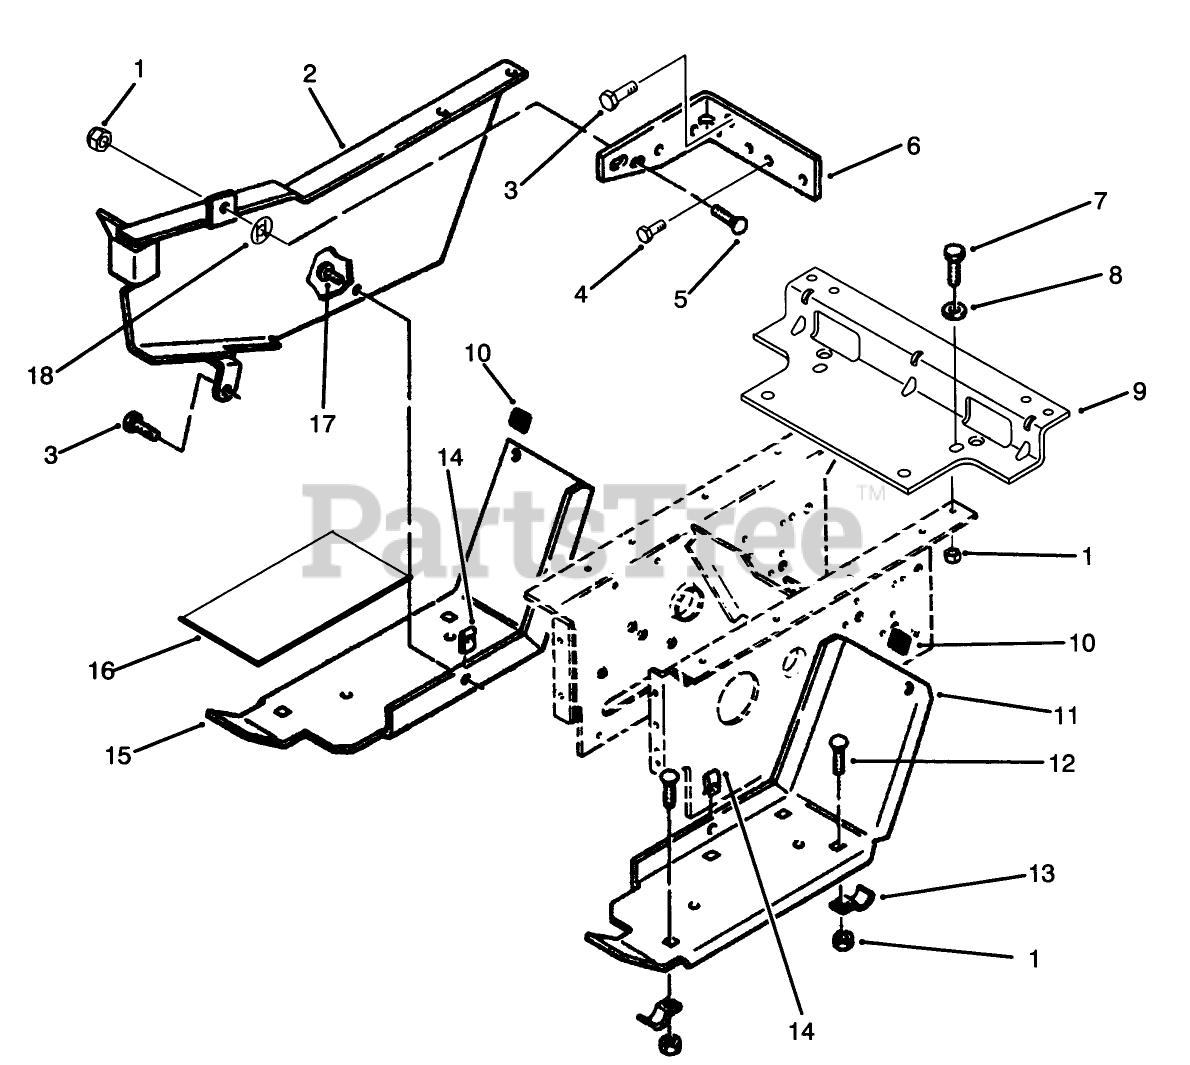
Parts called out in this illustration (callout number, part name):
1	NUT-LOCK, NI
2	GUARD - BELT WA *R
3	SCREW
4	Bolt
5	BOLT-CARR
6	BRACKET-BELT*B
7	SCREW-HH
8	WASHER-PLAIN
10	BUMPER
11	FOOTREST LH *R
12	BOLT-CARR
13	BRACKET
16	PAD FOOTREST
